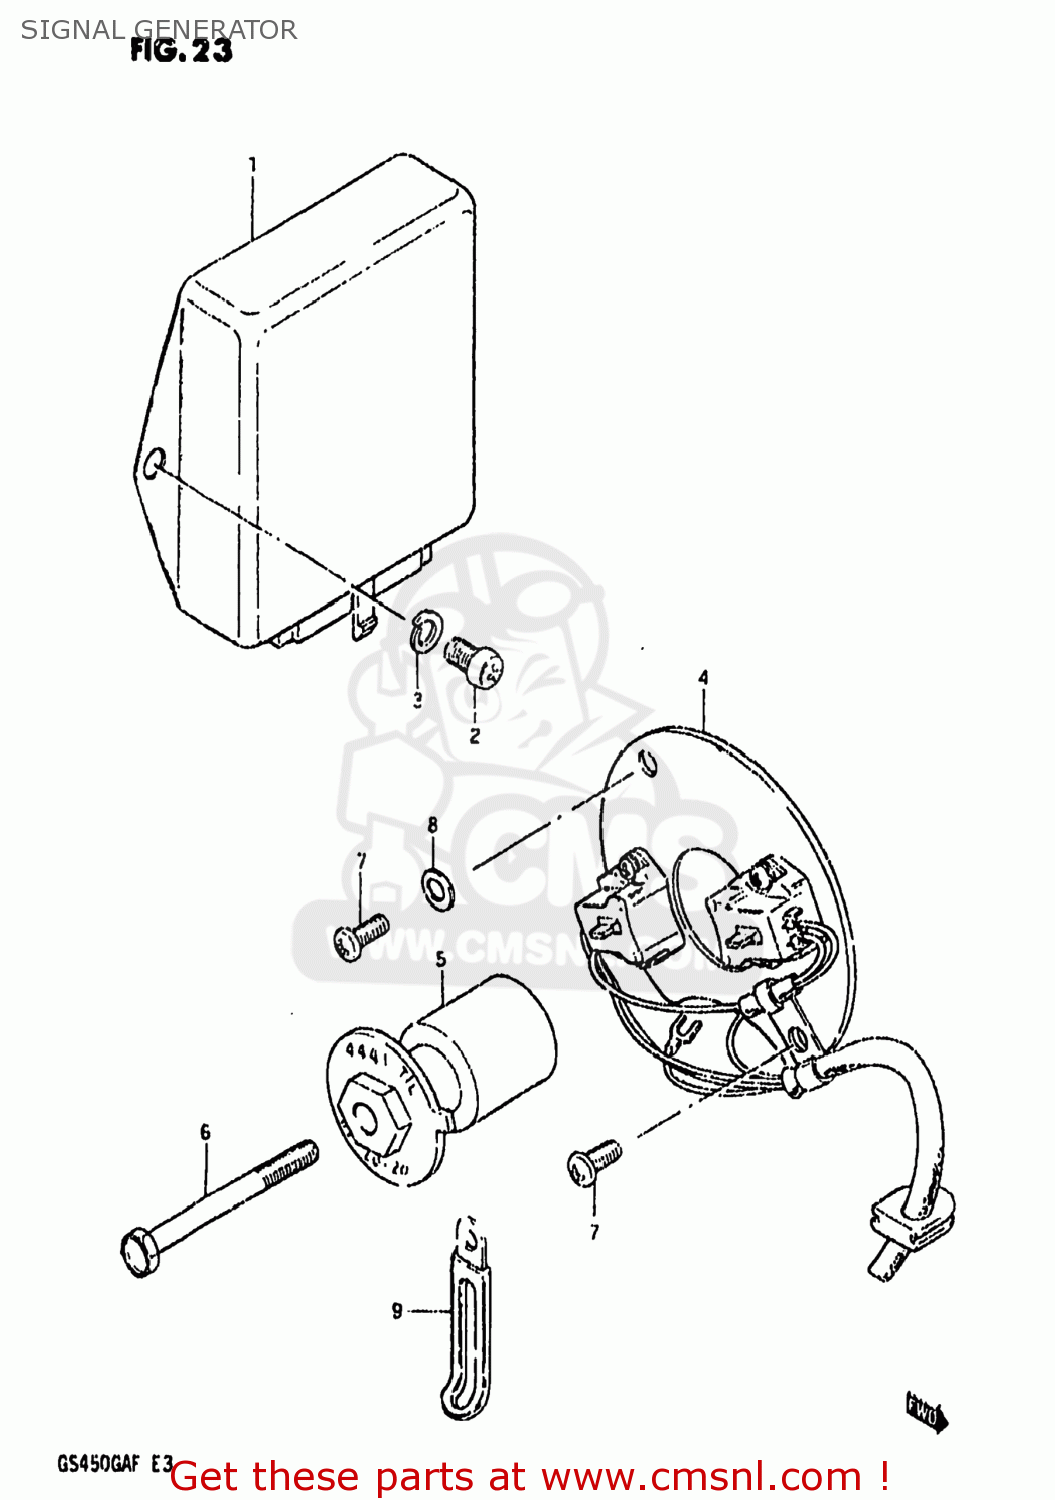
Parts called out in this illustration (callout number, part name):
1	IGNITOR UNIT
2	SCREW
3	LOCK WASHER
4	SIGNAL GENERATOR ASSEMBLY
5	GOVERNOR ASSEMBLY
6	BOLT
7	SCREW(5X12)
8	WASHER(5.5X10X0.8)
9	CLAMP L:35
